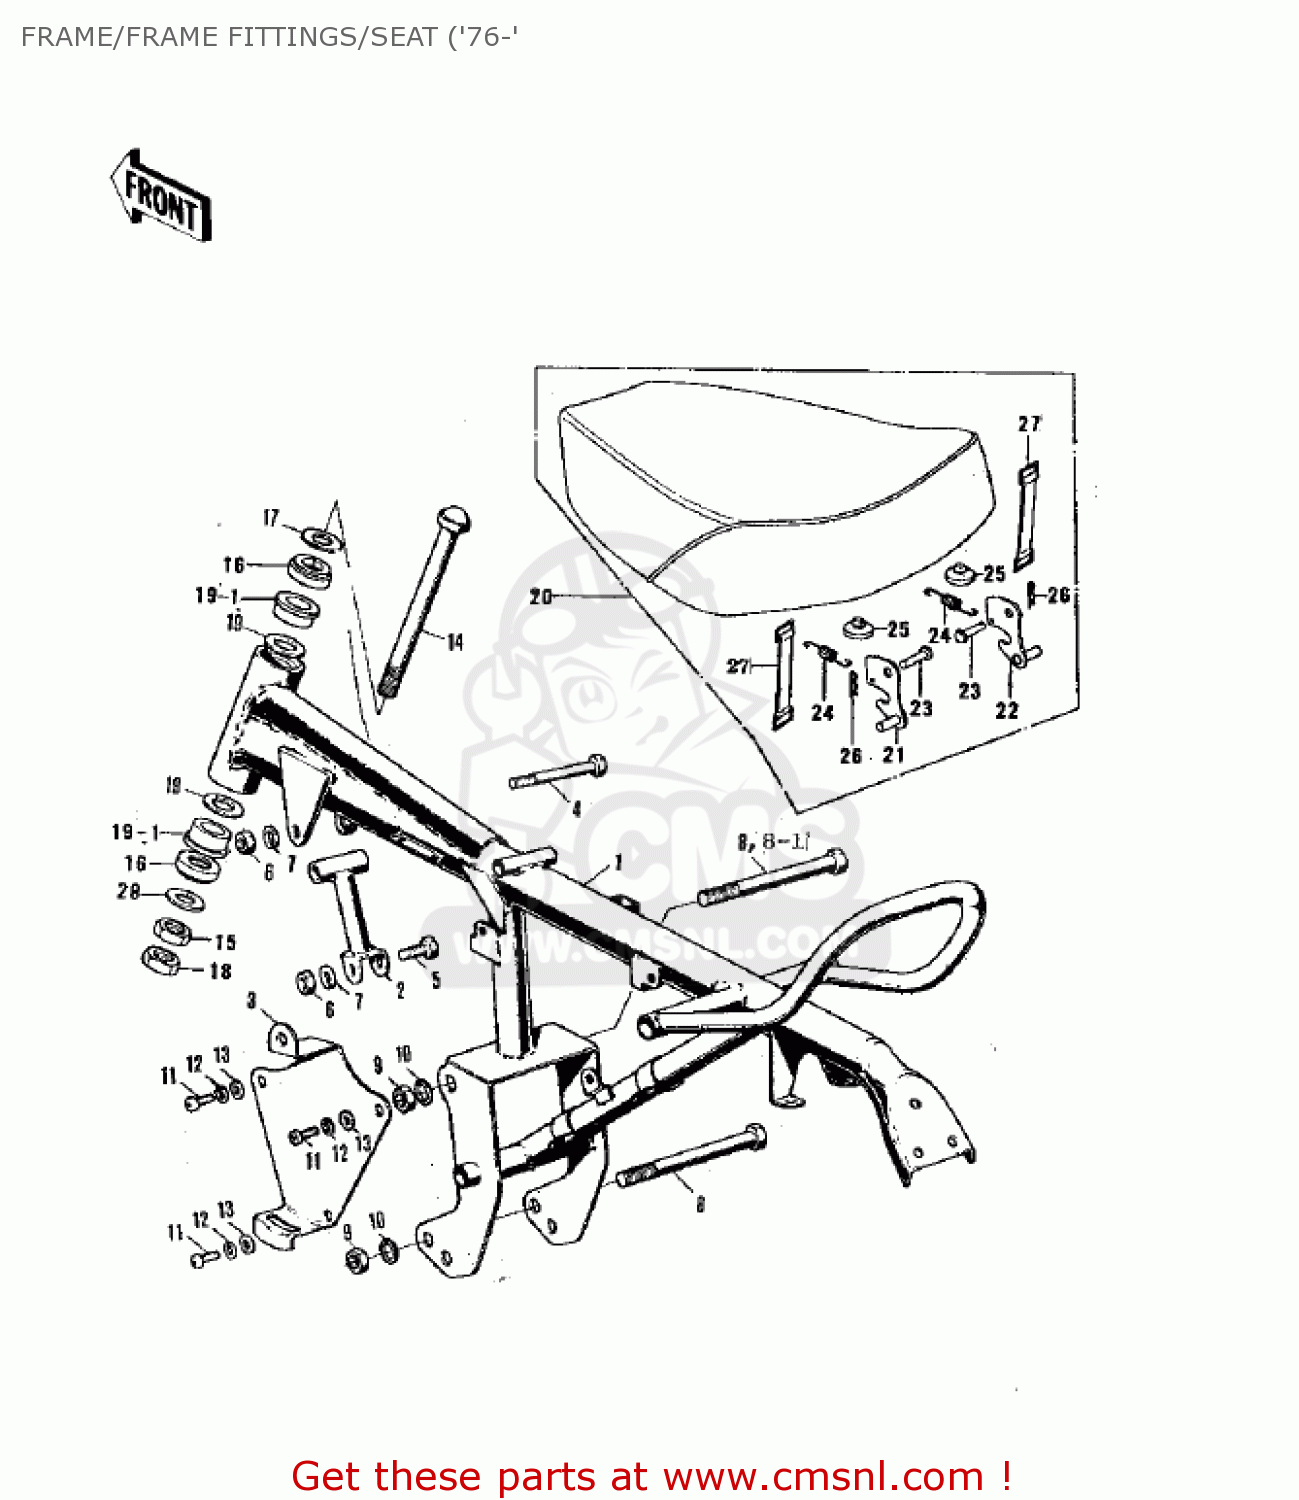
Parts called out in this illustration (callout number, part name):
1	FRAME
2	TUBE-DOWN
3	BRACKET-OIL TANK
4	BOLT,HEX HEAD,8X85
5	BOLT,FLANGED,8X40
6	NUT,8MM
7	WASHER-SPRING,8MM
8	BOLT,FLANGED,10X110
9	NUT,10MM
10	WASHER-SPRING,10MM
11	SCREW-PAN HEAD,6X12
12	WASHER-SPRING,6MM
13	WASHER-PLAIN-SMALL,6M
14	BOLT,STEERING HEAD
15	NUT-HEX-FINE,16MM
16	THRUST BEARING,#PC40
17	WASHER-PLAIN,16MM
18	NUT-HEX-FINE,16MM
19	COLLAR,STEERING
20	SEAT ASSY
21	HOOK,L.H
22	HOOK,R.H
23	PIN,BRAKE CABLE FIT
24	SPRING,HOOK
25	DAMPER,9X24X14
26	COTTER
27	BAND,L=50
28	WASHER-PLAIN,16MM
